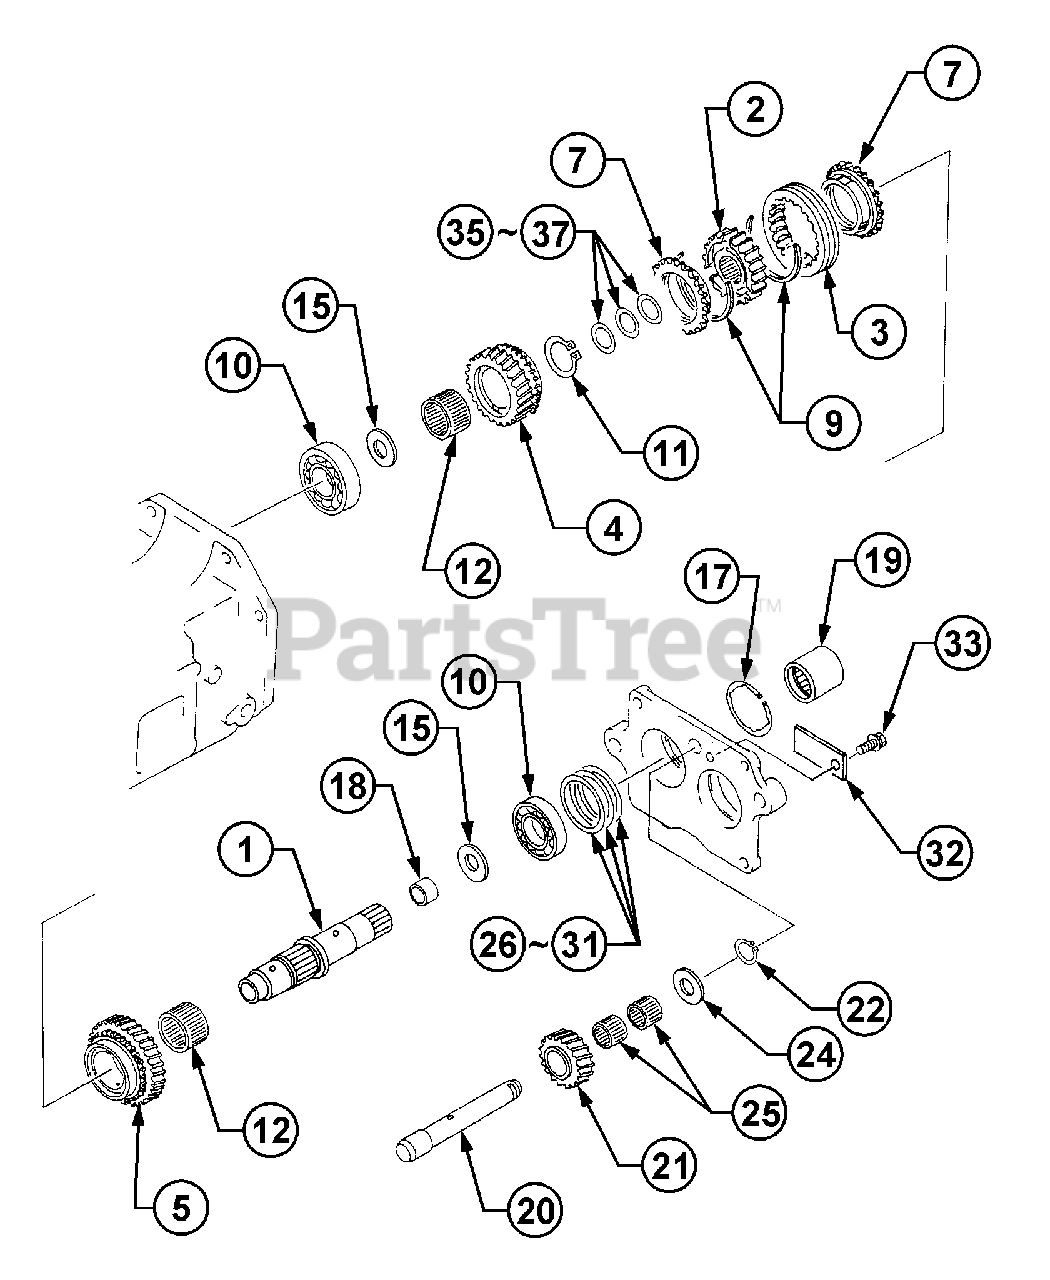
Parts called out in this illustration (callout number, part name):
2	Hub
3	Sleeve
10	Bearing, Ball
12	Bearing, Needle
25	Bearing, Needle
26	Liner, t=0.15
33	Bolt, w/Washer
